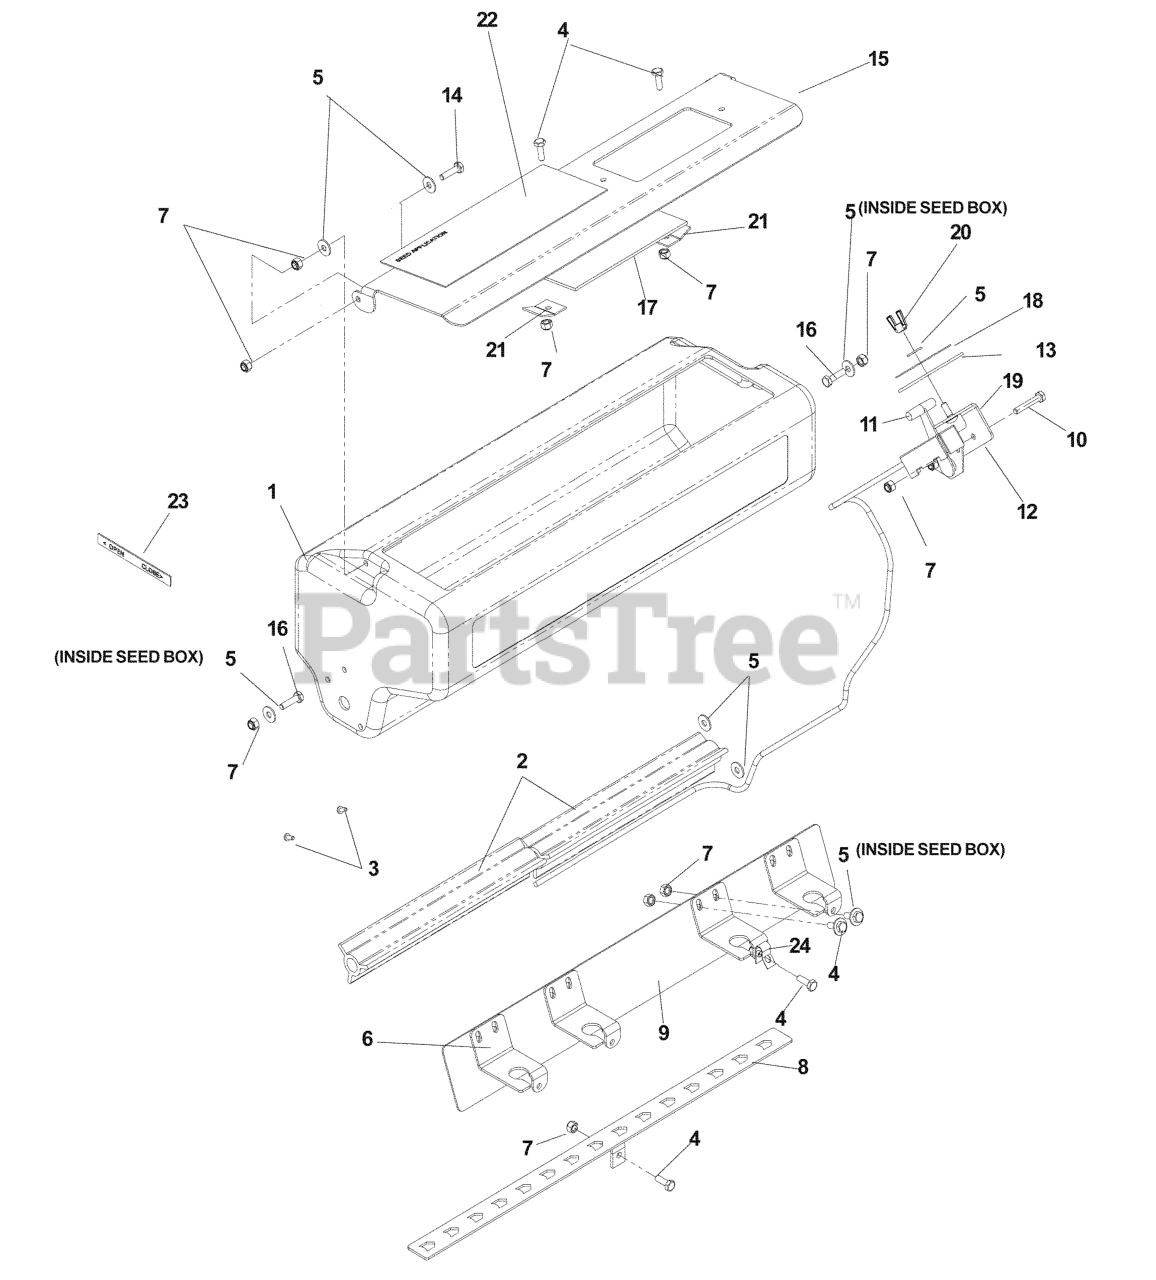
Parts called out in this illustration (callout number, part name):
1	SEED BOX CHARCOAL GREY
3	HR STRIP, 1/8 X 1
4	HCS 1/4C X 3/4 HCS
5	WASHER 1/4 FLAT
7	NUT.1/4-20.HEX.NYLOC.ZD
10	SCW 1/4-20 X 1-1/2 HEX
11	PUSH/PULL ASSY CONTROL
14	HCS 1/4C X 1
15	SEED DOOR ORANGE
16	HCS 1/4 X 1
17	SEED WINDOW
18	DECAL, SEED DIAL
19	RHSNB 1/4C X 3/4
20	WING NUT 1/4
21	WINDOW CLIP
22	DECAL, SEED APPL
23	DECAL, OPEN/CLOSE
24	PUSH PULL CONTROL CLAMP
